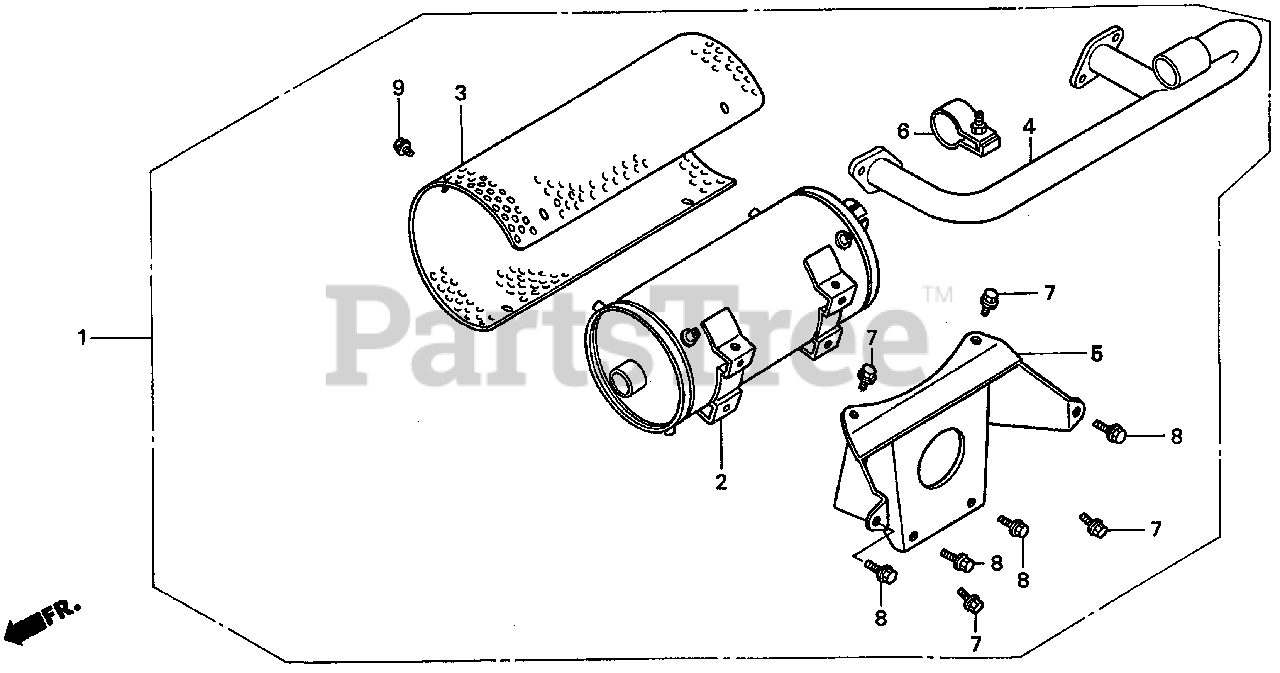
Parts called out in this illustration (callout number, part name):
1	MUFFLER KIT (HIGH-B) (N/A: SEE COMPONENTS)
2	MUFFLER (HIGH)
3	PROTECTOR, MUFFLER (HIGH)
4	PIPE, EX. (HIGH-L)
5	STAY, MUFFLER (HIGH)
6	BAND ASSY.
7	BOLT, FLANGE (6X8)
8	BOLT, FLANGE (8X14)
9	BOLT, FLANGE (8X20)
